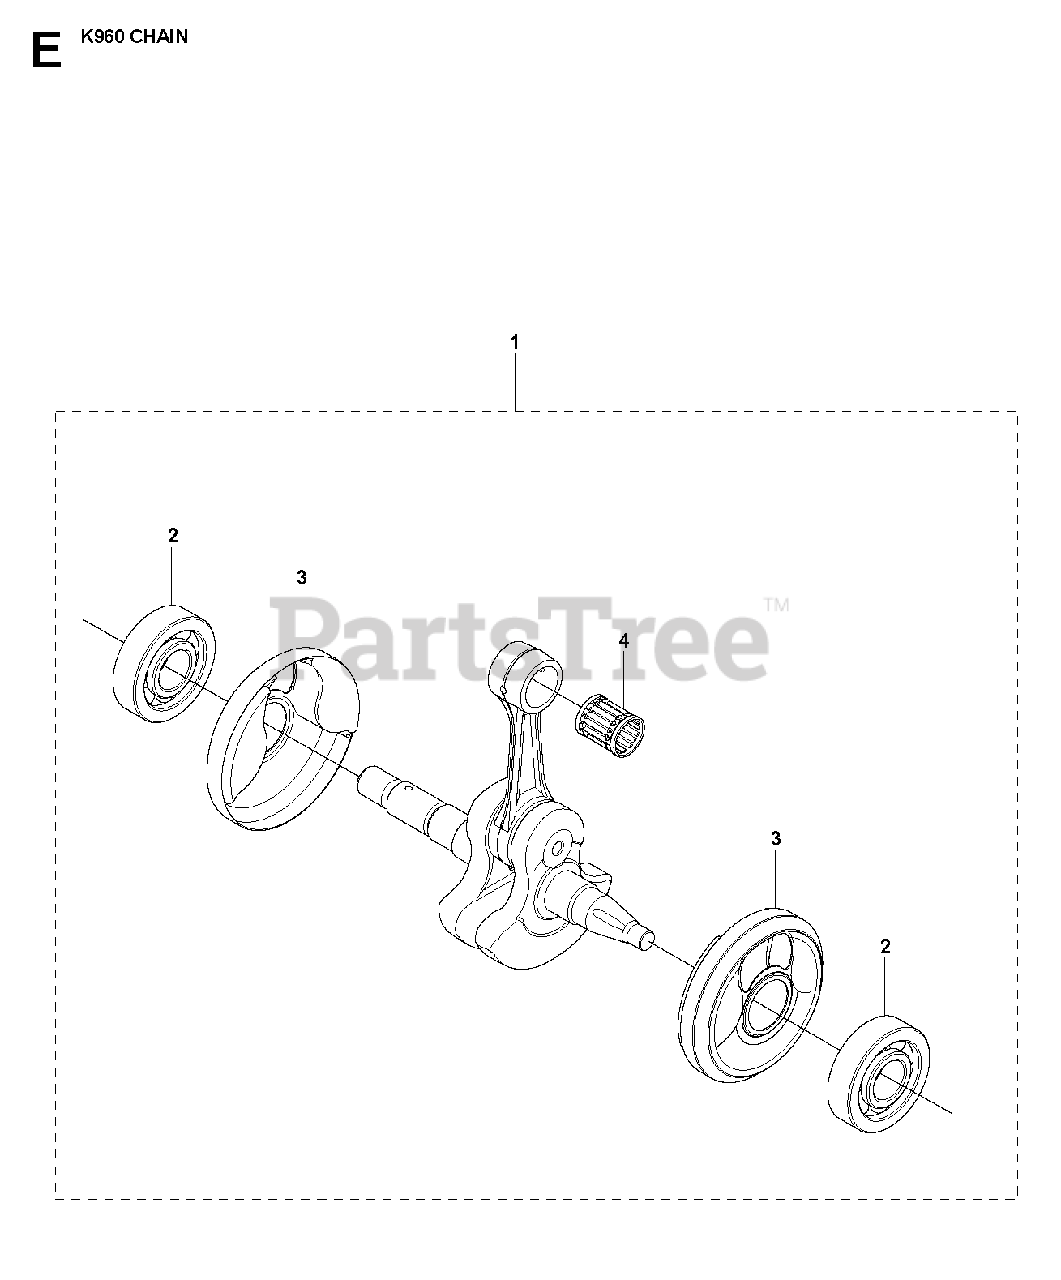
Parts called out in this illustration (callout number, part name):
1	CRANKSHAFT ASSYIncl. 2 - 4
2	BALL BEARING
4	NEEDLE BEARING
